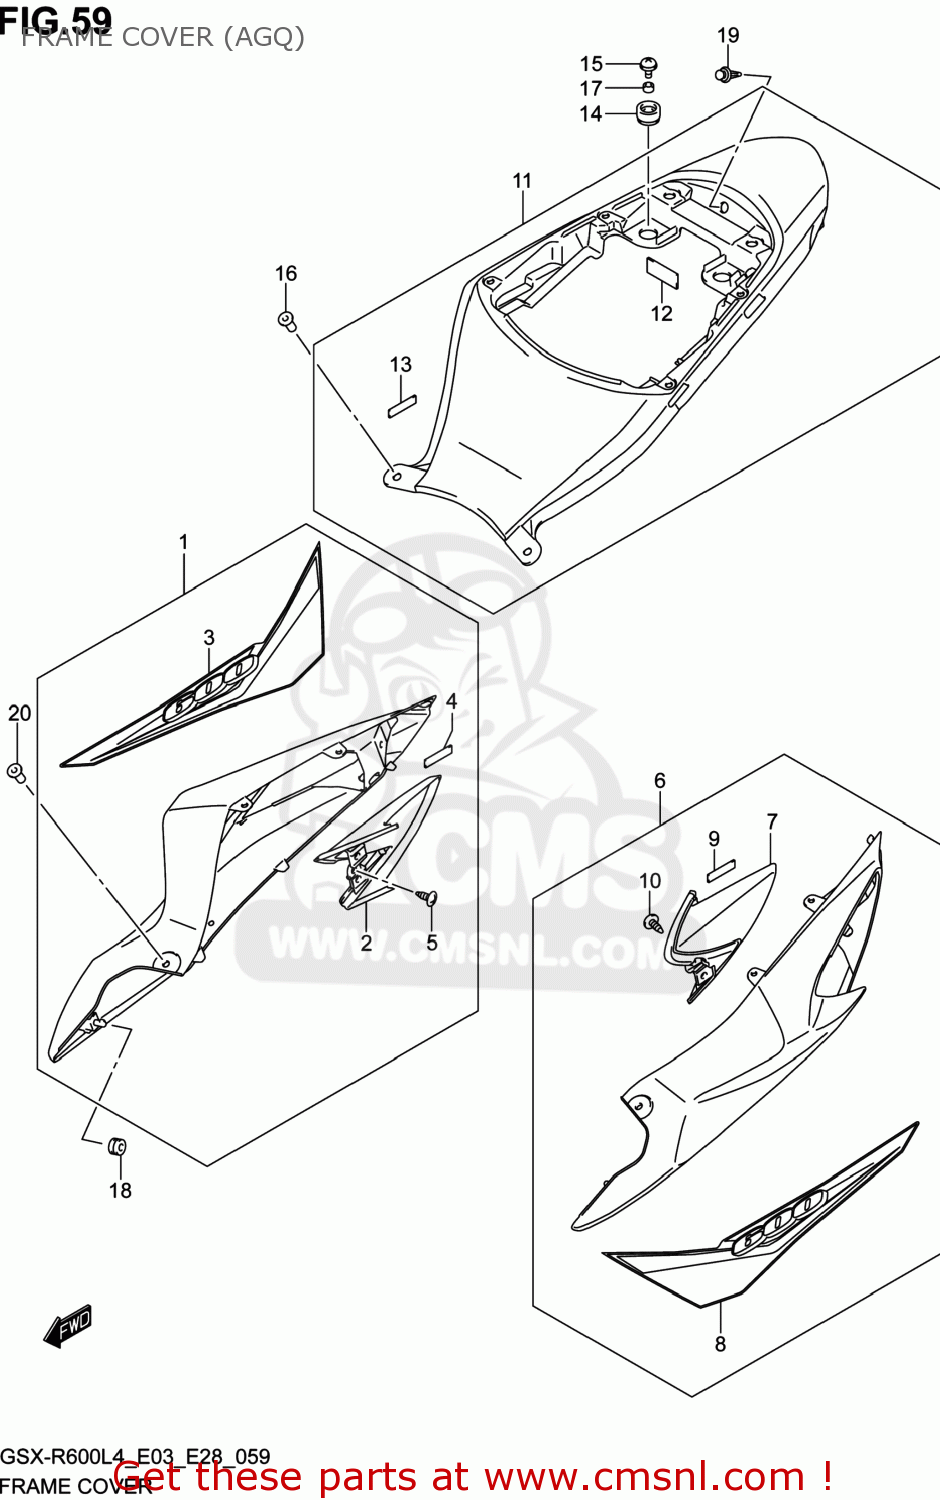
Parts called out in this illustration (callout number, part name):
1	COVER ASSY,FRAME,R
2	COVER,FRAME RR,R
3	TAPE,FRAME COVER,R
4	TAPE(6X25X0.13)
5	SCREW
6	COVER ASSY,FRAME,L
7	COVER,FRAME RR,L
8	TAPE,FRAME COVER,L
9	TAPE(6X25X0.13)
10	SCREW
11	COVER ASSY,FRAME CTR
12	CUSHION
13	TAPE(6X25X0.13)
14	CUSHION,FRAME COVER RR
15	SCREW(6X16)
16	NUT
17	SPACER(6.5X10X7)
18	CUSHION
19	CLIP(BLACK)
20	SCREW
